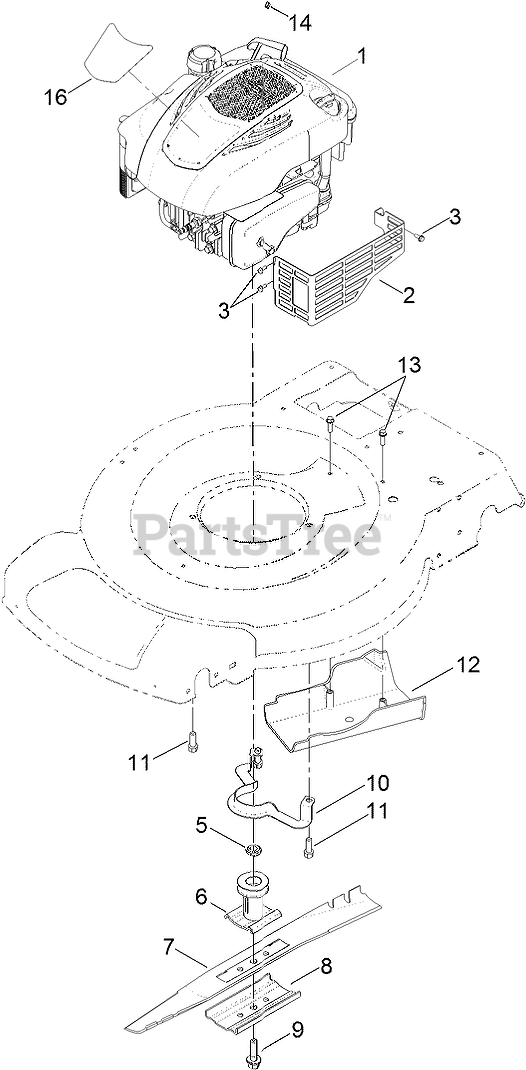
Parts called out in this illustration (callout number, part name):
2	SHIELD-MUFFLER
3	SCREW-TAPTITE
5	Spacer-Driver
6	DRIVER-BLADE
7	BLADE-22 INCH
8	SUPPORT-BLADE
9	BOLT-BLADE
10	Guide-Belt
11	SCREW-TAPTITE
12	COVER-BELT
13	SCREW-HWH
14	STOP-ROPE
16	DECAL-SHROUD
